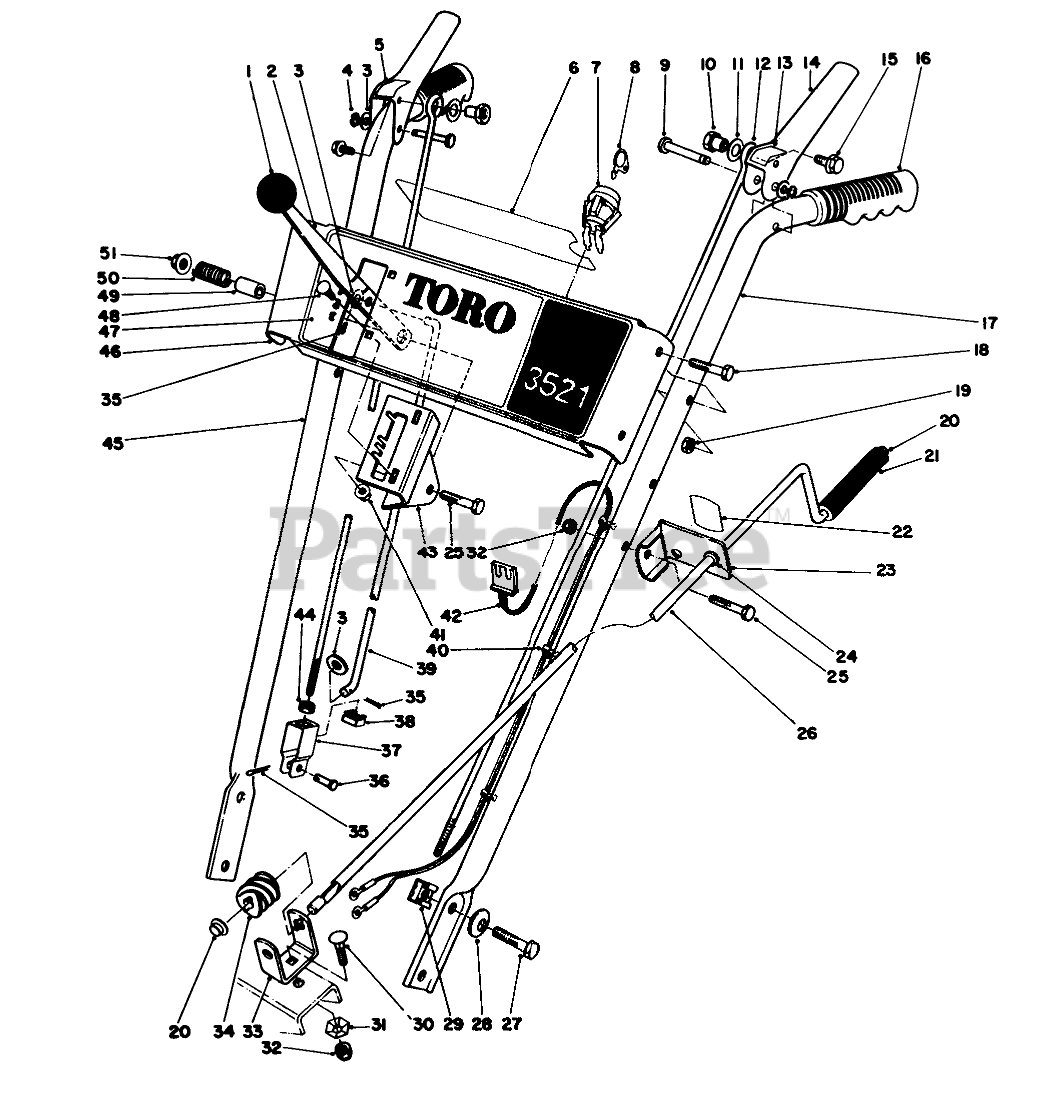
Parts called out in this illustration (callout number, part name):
2	SPEED SELECTOR B
3	WASHER-PLAIN
4	RING-CLIP
5	AUGER DRIVE DECAL
6	BACK DECAL
7	SWITCH
8	Key
9	PIN-LEVER, CONTROL
10	Post-Linkage Mounting
11	WASHER-FLAT
12	LINK-UPPER
13	DECAL
14	Handle-Control
15	SCREW-HHF
16	Grip
17	LEFT HANDLE
18	SCREW-HH
19	NUT-LOCK, CONE
20	RETAINER-PUSH ON
21	GRIP-CONTROL, CHUTE
22	CHUTE DECAL
23	Bracket-Chute Control (Incl. Ref. #22 & 24)
24	Bushing
25	SCREW-HH
26	ROD-CONTROL, CHUTE
27	SCREW-HH
28	WASHER-BELLEVILLE
30	BOLT-CARR
31	WASHER-LOCK
32	NUT-LOCK, NI
33	BRACKET-WORM
34	GEAR-WORM, CHUTE
35	Cotter Pin
36	PIN-CLEVIS
37	CLEVIS
38	NUT-RETAINED
39	ROD-SELECTOR, SPEED
40	Mount-Wire
41	NUT-HHF
42	Wire Harness Assembly (Incl. Ref. #40)
43	Mount-Speed Selector
44	NUT-JAM
45	RIGHT HANDLE
46	ESCUTCHEON PLT B
47	Decal-3521
48	SCREW-CARRIAGE
49	SPACER
50	SPRING
51	NUT-HF
